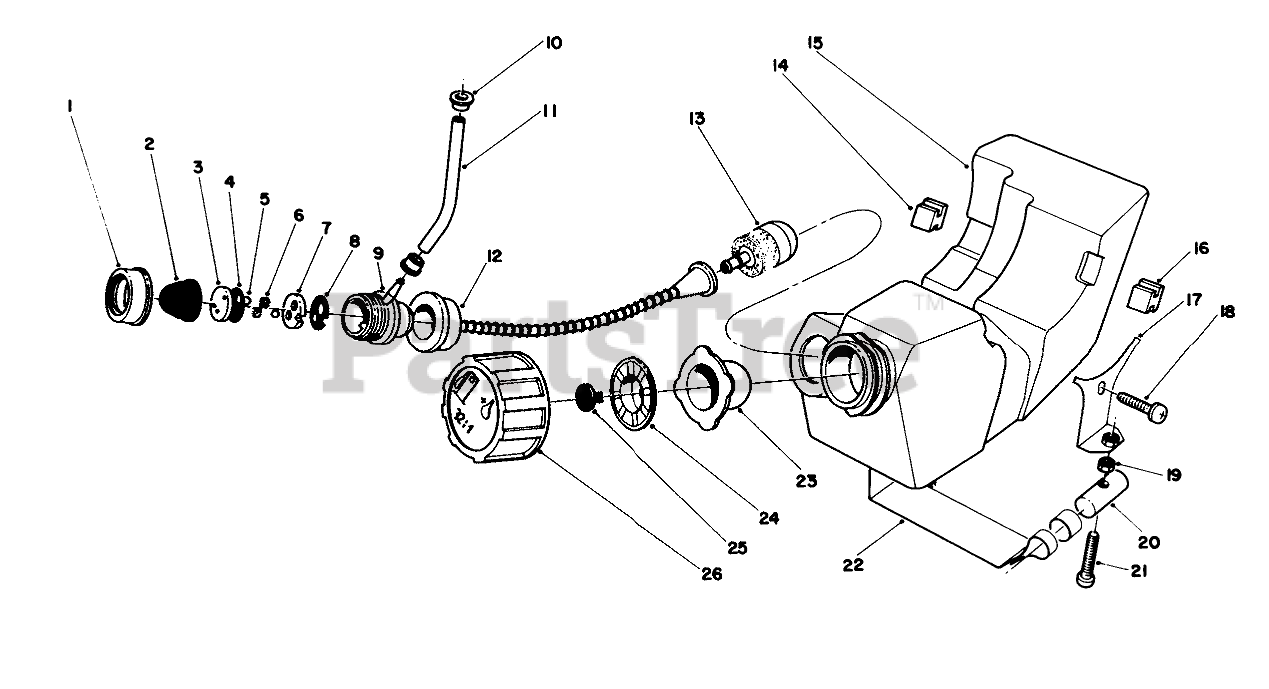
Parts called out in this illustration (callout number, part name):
1	PUMP CAP
3	SEAT VALVE
4	GASKET
6	SPONGE
7	SEAT VALVE
8	GASKET
9	Primer Pump Assembly (Incl. Ref. #1-8)
11	TUBE, FUEL
12	SUCTION HOSE
13	FUEL FILTER
15	Fuel Tank Assembly (Incl. Ref. #1-9, 12, 13, 23-26)
17	Hanger-Tank
18	Screw
21	Screw
22	BAND, TANK
23	GASKET - PACKING
24	HOLDER
25	BREATHER VALVE
26	TANK CAP
